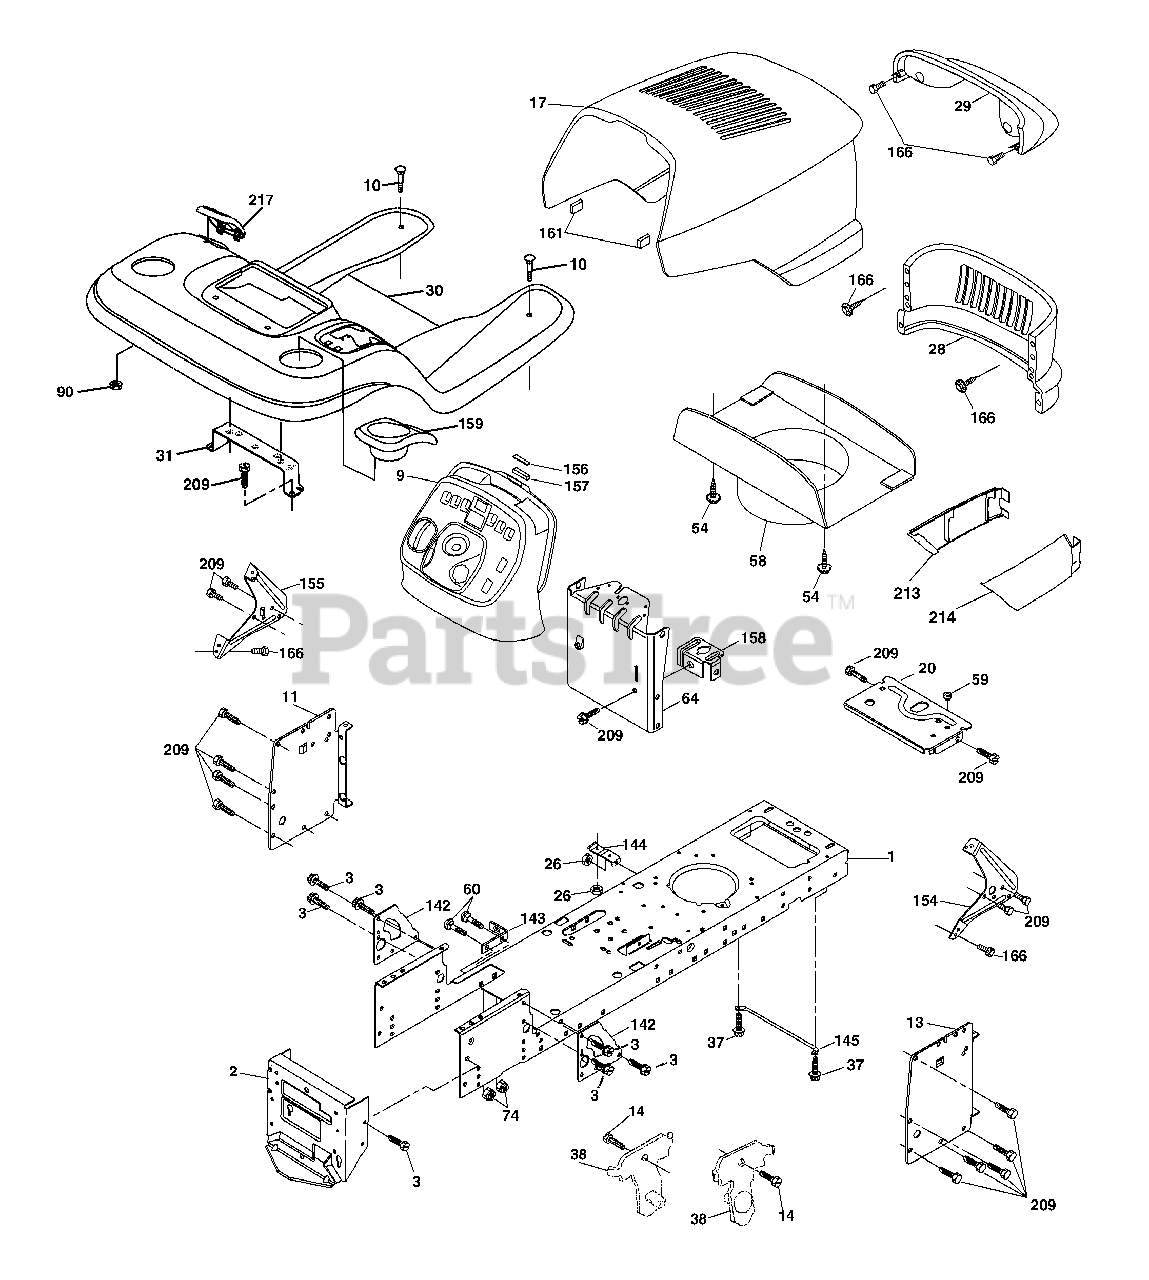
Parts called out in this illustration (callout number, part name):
1	Chassis
2	Drawbar
3	Screw 3/8-16x3/4
9	Dash
10	Bolt 3/8-16 x 1
11	Panel Dash Lh
13	Panel Dash Rh
14	Screw Thdrol 3/8-16 x 1/2
17	Hood
20	Plate Battery
26	Nut Lock Hex W/Ins 3/8-16 Unc
28	Grille
29	Light Asm. Bar
30	Fender
31	Bracket Fender
37	Screw Thdrol 6/16-18 x 1/2 TYT
38	Bracket, Asm. Pivot Mower Rear
54	Screw Hex Wshd 8-18 x 7/8
58	Duct Hood
59	Bushing Snap
60	Bolt Rd Hd Sqnk 3/8-16 Unc x 3/4
64	Dash Lower
74	Nut Crownlock 3/8-16 Unc
90	Nut Self-Thd Wsh-Hd 1/4 Zinc
142	Plate Reinforcement STLT
143	Bracket Swaybar Chassis
144	Bracket Footrest
145	Rod Pivot Chassis/Hood
154	Bracket Dash Rh
155	Bracket Dash Lh
156	Striker Plate
157	Magnet Stealth
158	Bracket Parking Brake
159	Cupholder
161	Extrusion Bumper
166	Screw Hw Hd Hi-Lo #13-16 x 3/4
209	Screw Hexwsh Thdrol 3/8-16 x 3/4
213	Skirt Grille LH
214	Skirt Grille RH
217	Console Fuel Window
